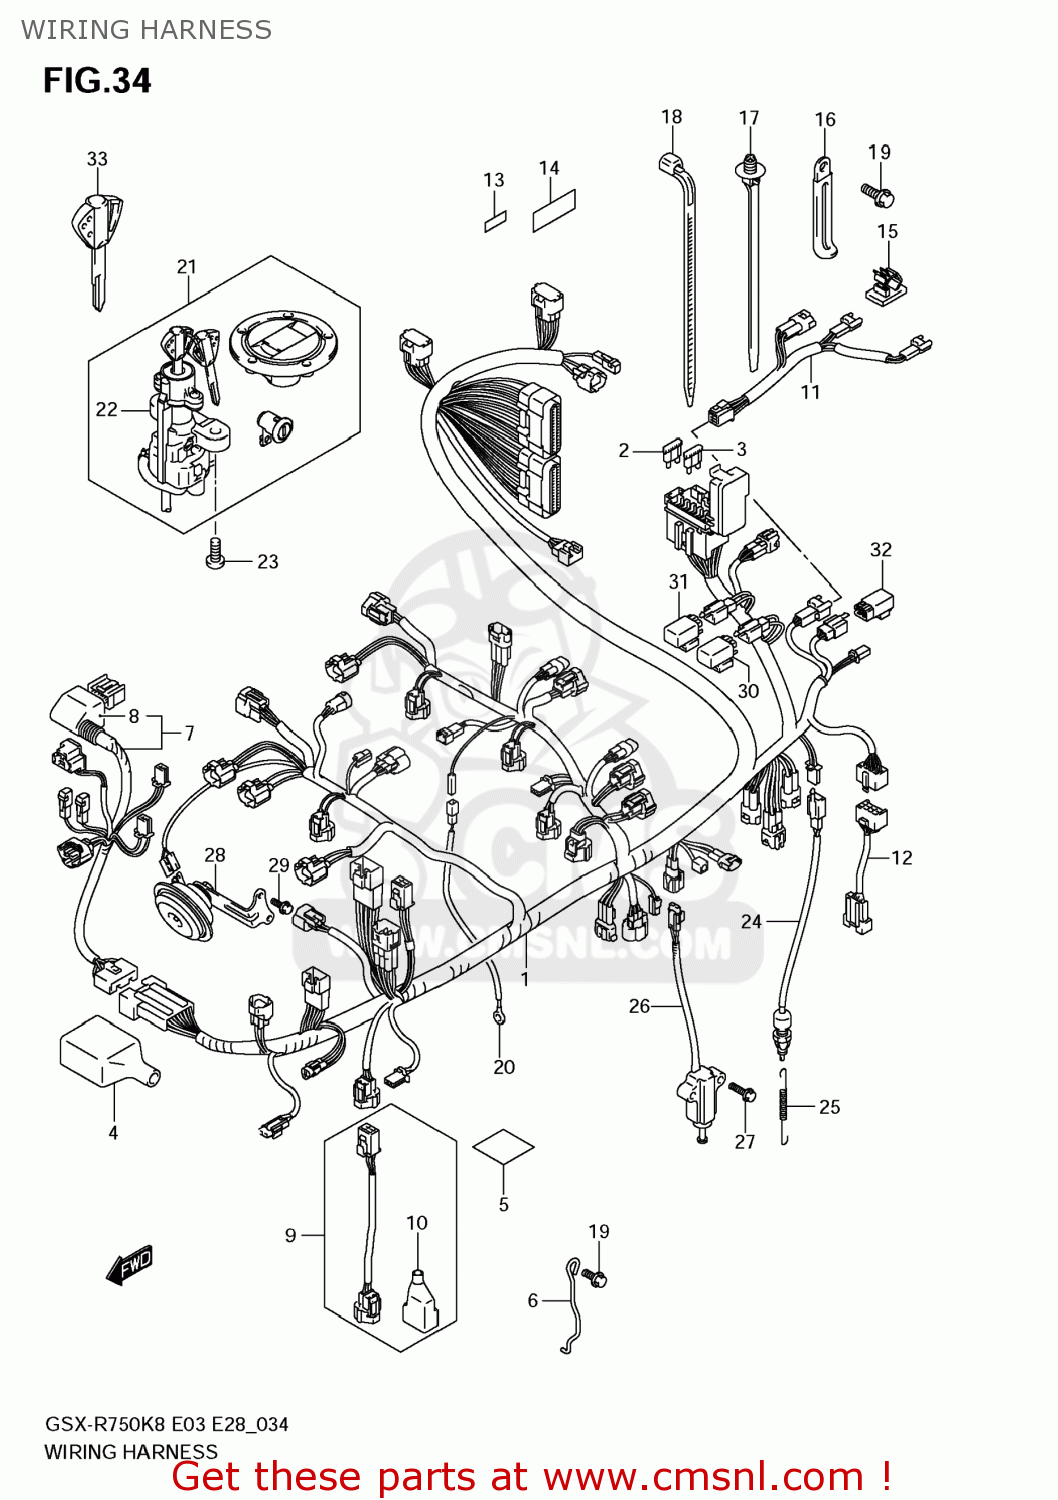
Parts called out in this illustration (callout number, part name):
1	HARNESS,WIRING NO.1
2	FUSE(10A)
3	FUSE(15A)
4	COVER
5	PROTECTOR(30X80X1)
6	GUIDE,WIRING HARNESS
7	HARNESS,WIRING NO.2
8	COVER,CONNECTOR
9	WIRE,ACTUATOR LEAD
10	COVER,SUB THROTTLE ACTUATOR
11	WIRE,RR COMB
12	WIRE,RELAY LEAD
13	PROTECTOR,WIRING HARNESS
14	PROTECTOR,WIRING HARNESS
15	CLAMP
16	CLAMP(L:45)
17	CLAMP(L:154)
18	CLAMP(L:125)
19	BOLT
20	WIRE,OIL PRESSURE SWITCH LEAD
21	LOCK SET
22	LOCK ASSY,STEE
23	BOLT(8X20)
24	SWITCH ASSY,STOP LAMP
25	SPRING
26	SWITCH ASSY,SIDE STAND
27	BOLT
28	HORN ASSY
29	BOLT
30	RELAY ASSY
31	RELAY ASSY
32	RELAY ASSY,HEADLAMP
33	KEY,BLANK(IMMOBII)
